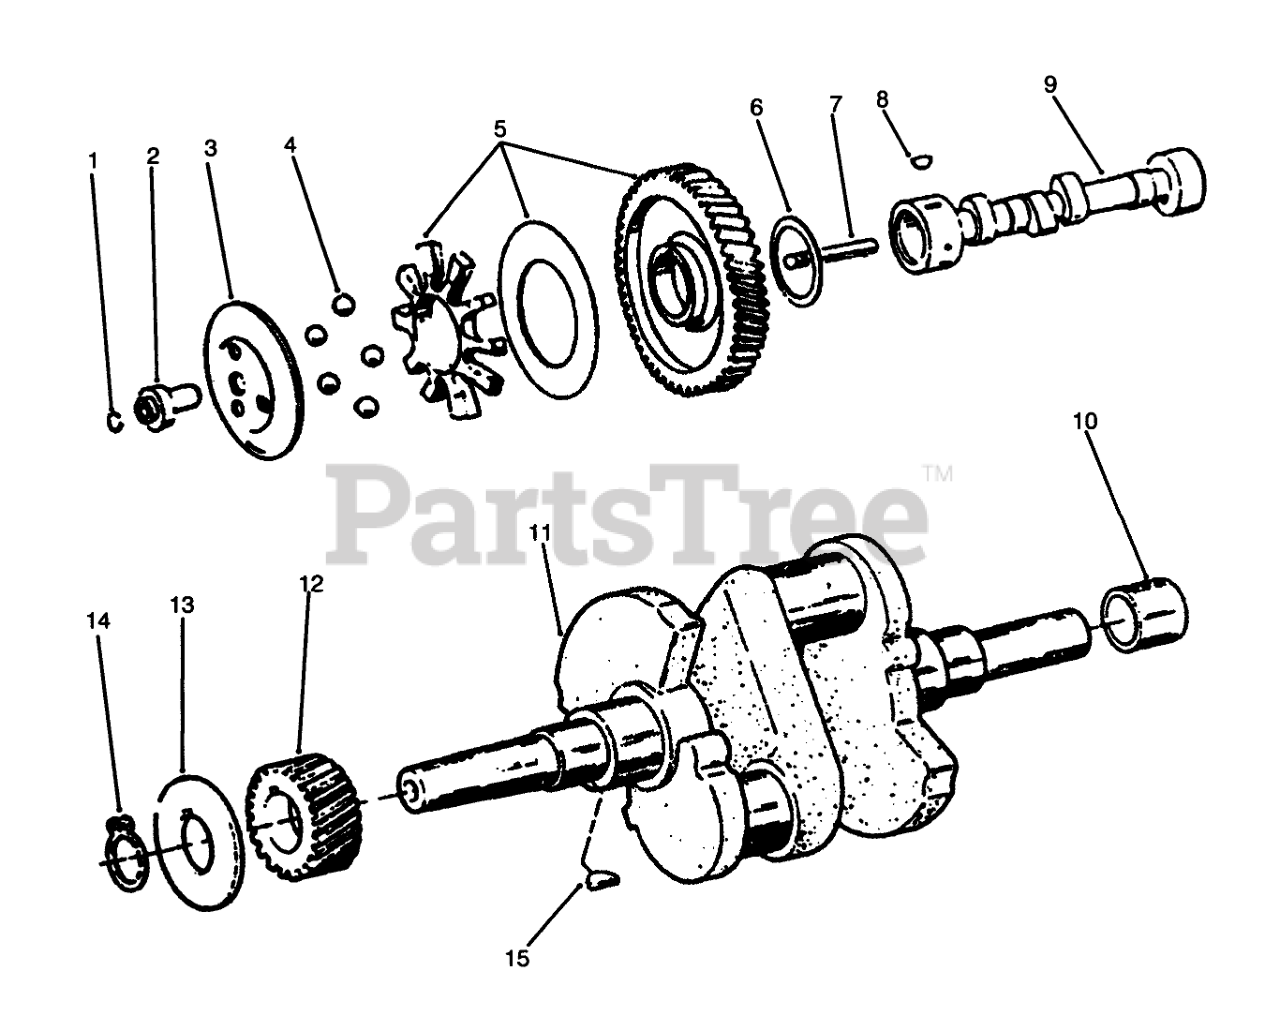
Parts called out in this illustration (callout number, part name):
2	HUB-GOVERNOR CUP
3	CUP-GOVERNOR
4	BEARING
5	Gear-Camshaft (Incl. Gear, Spacer, & Plate)
6	WASHER-THRUST
7	PIN-CENTER
9	Camshaft (Incl. Ref. #7)
10	BEARING SLEEVE
11	Crankshaft (Incl. Ref. #15)
13	WASHER
